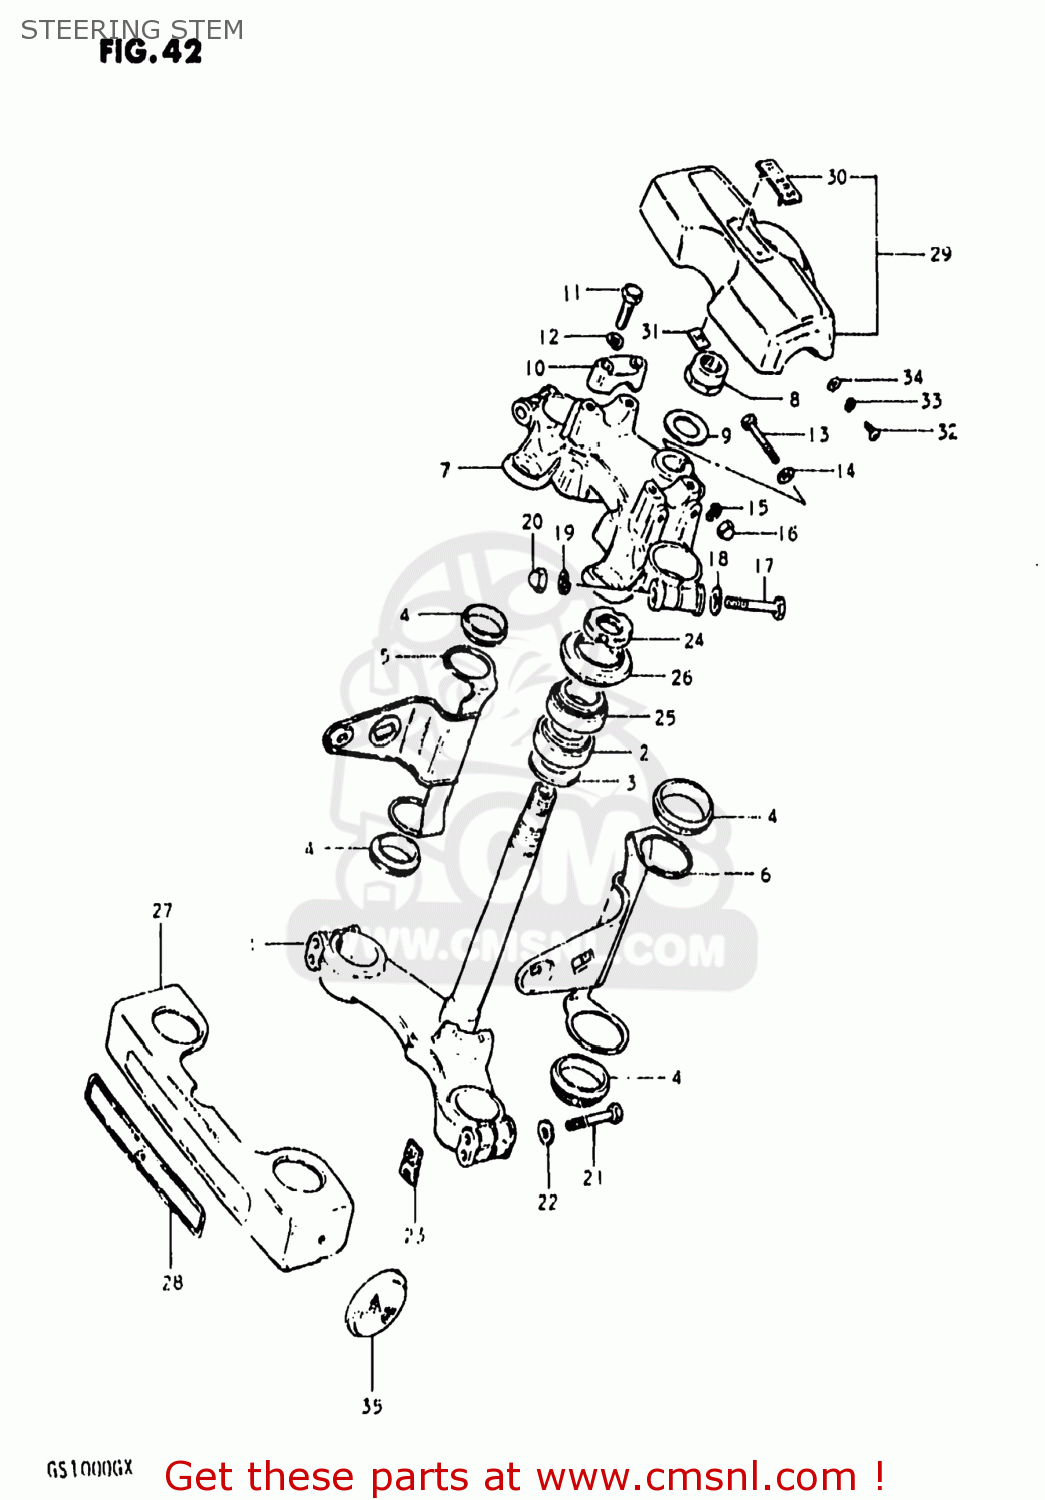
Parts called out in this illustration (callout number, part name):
1	STEM,STEERING
2	BEARING
3	WASHER,THRUST
4	CUSHION,HEADLAMP BRACKET
5	BRACKET,HEADLAMP,RIGHT
6	BRACKET,HEADLAMP,LEFT
7	HEAD,STEERING STEM
8	NUT,FR FORK UPR BRACKET
9	WASHER
10	HOLDER,HANDLE(BLACK)
11	BOLT
12	LOCK WASHER
13	BOLT 8X50
14	WASHER
15	LOCK WASHER
16	NUT
17	BOLT 10X55
18	WASHER
19	LOCK WASHER
20	NUT, LOWER LH
21	BOLT 8X55
22	WASHER
23	NUT,FR FORK INNER TUBE
24	NUT,STEERING STEM(25X44X10)
25	TAPER,ROLLER BEARING
26	DUST SEAL,STEERING,UPPER
27	COVER,FRONT FORK
28	EMBLEM
29	PAD,HANDLEBAR
30	EMBLEM,HANDLE COVER PAD
31	NUT
32	SCREW
33	LOCK WASHER
34	WASHER
35	REFLEX REFLECTOR,RR
